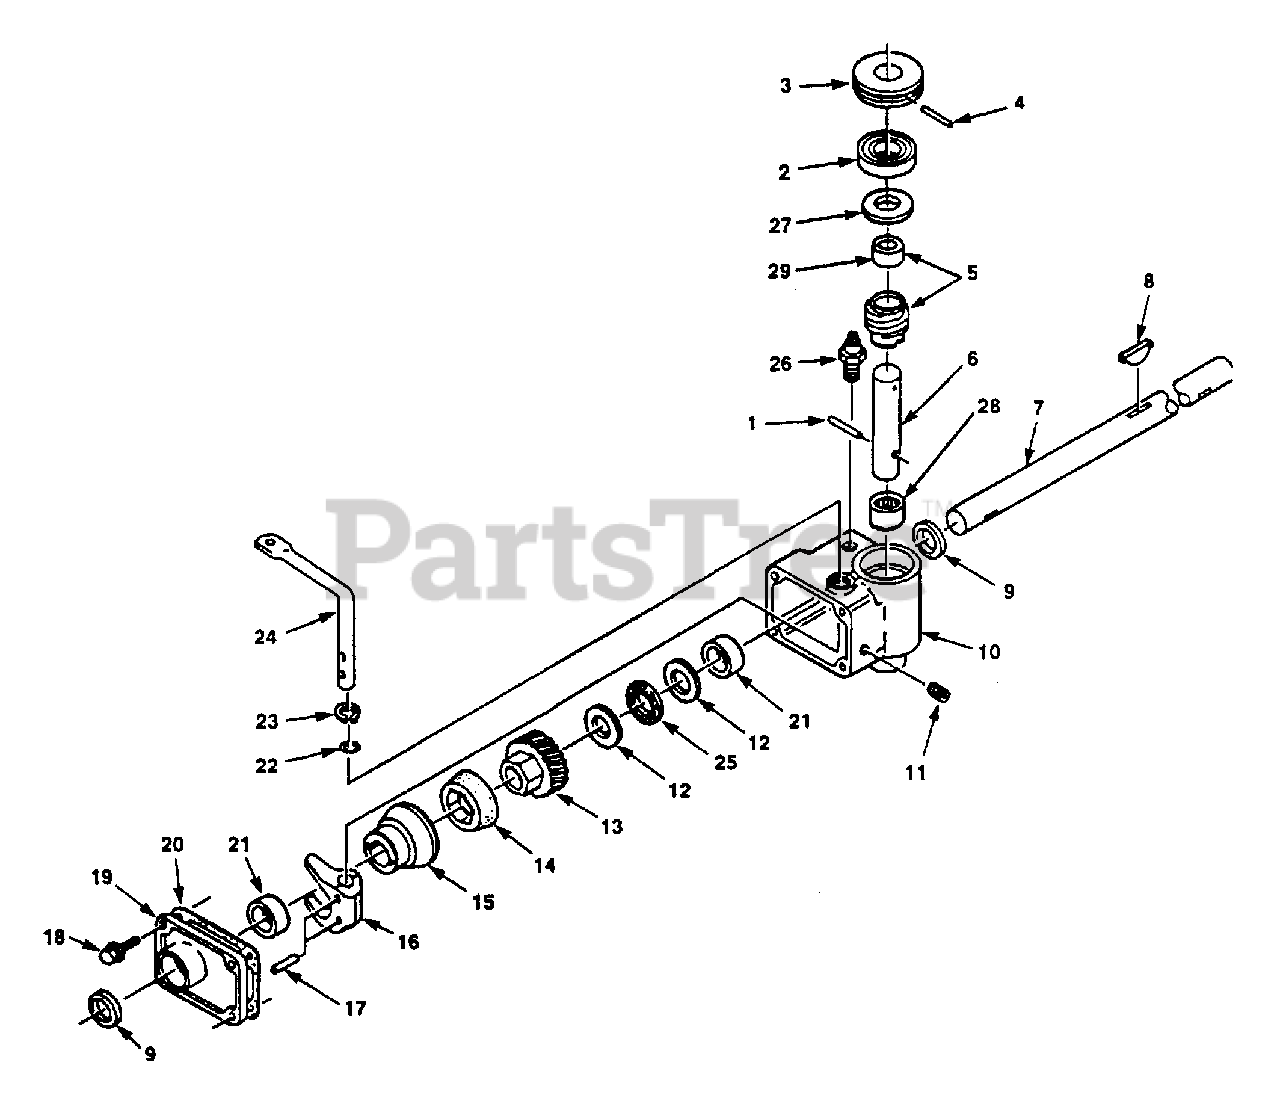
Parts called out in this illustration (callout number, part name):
1	PIN
2	BEARING, BALL
3	PULLEY
4	PIN
5	WORM & SPACER
6	SHAFT, WORM
7	DRIVESHAFT
8	KEY - 1/8 X 1/2"
9	SEAL
10	GEAR REDUCER HOUSING ASSY
11	PLUG - PIPE
12	RACE - Bearing
13	GEAR - WORM
14	CONE - Friction
15	DRUM, CLUTCH
16	FORK - Shift
17	PIN
18	SCREW - 1/4-20 X 7/8"
19	LID, GEAR CASE
20	GASKET
21	BUSHING
22	O-RING
23	RING, RETAINING
24	LEVER, SHIFT
25	BEARING - THRUST
26	VENT
27	WASHER
28	BEARING, NEEDLE
29	SPACER
